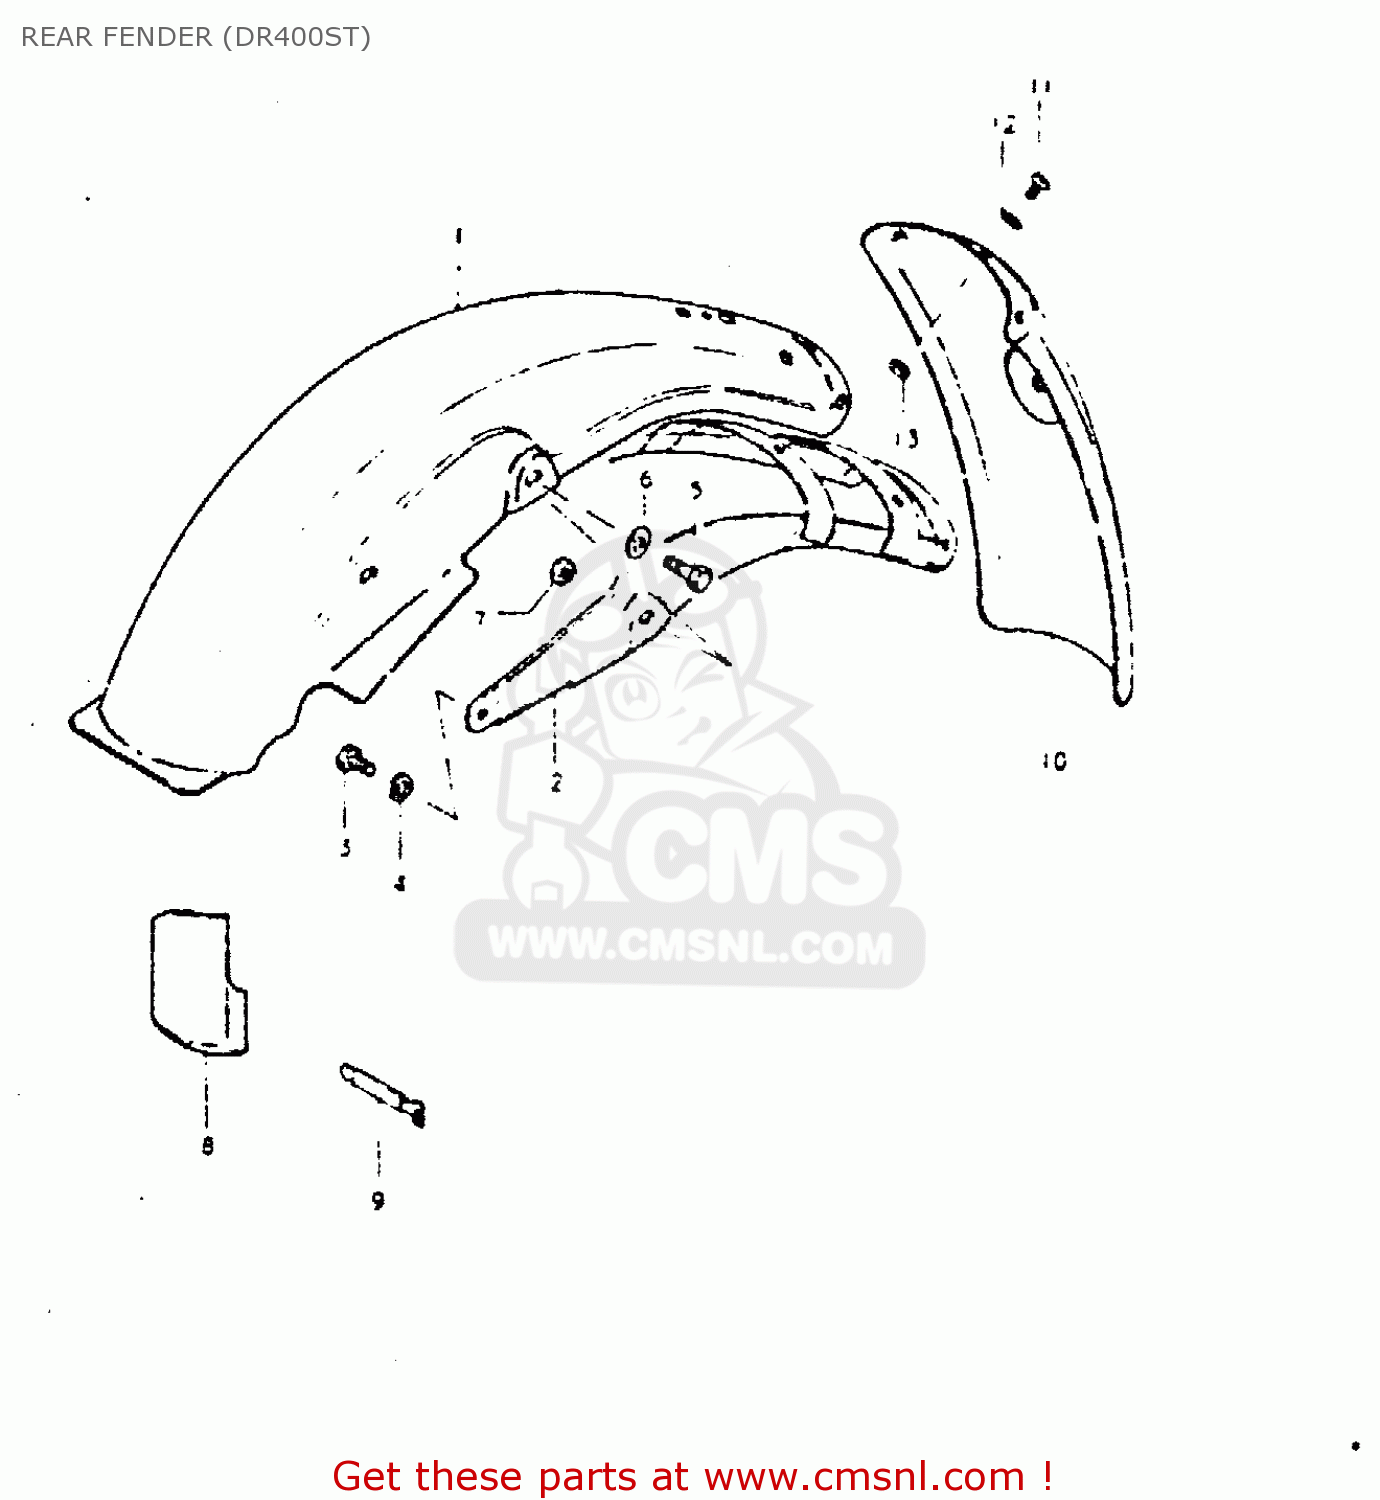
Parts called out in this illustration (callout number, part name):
1	FENDER, REAR
2	REINFORCEMENT,REAR FENDER
3	BOLT
4	LOCK WASHER
5	BOLT (8X30)
6	WASHER
7	NUT
8	MUD GUARD,REAR FENDER
9	CLAMP L:110
